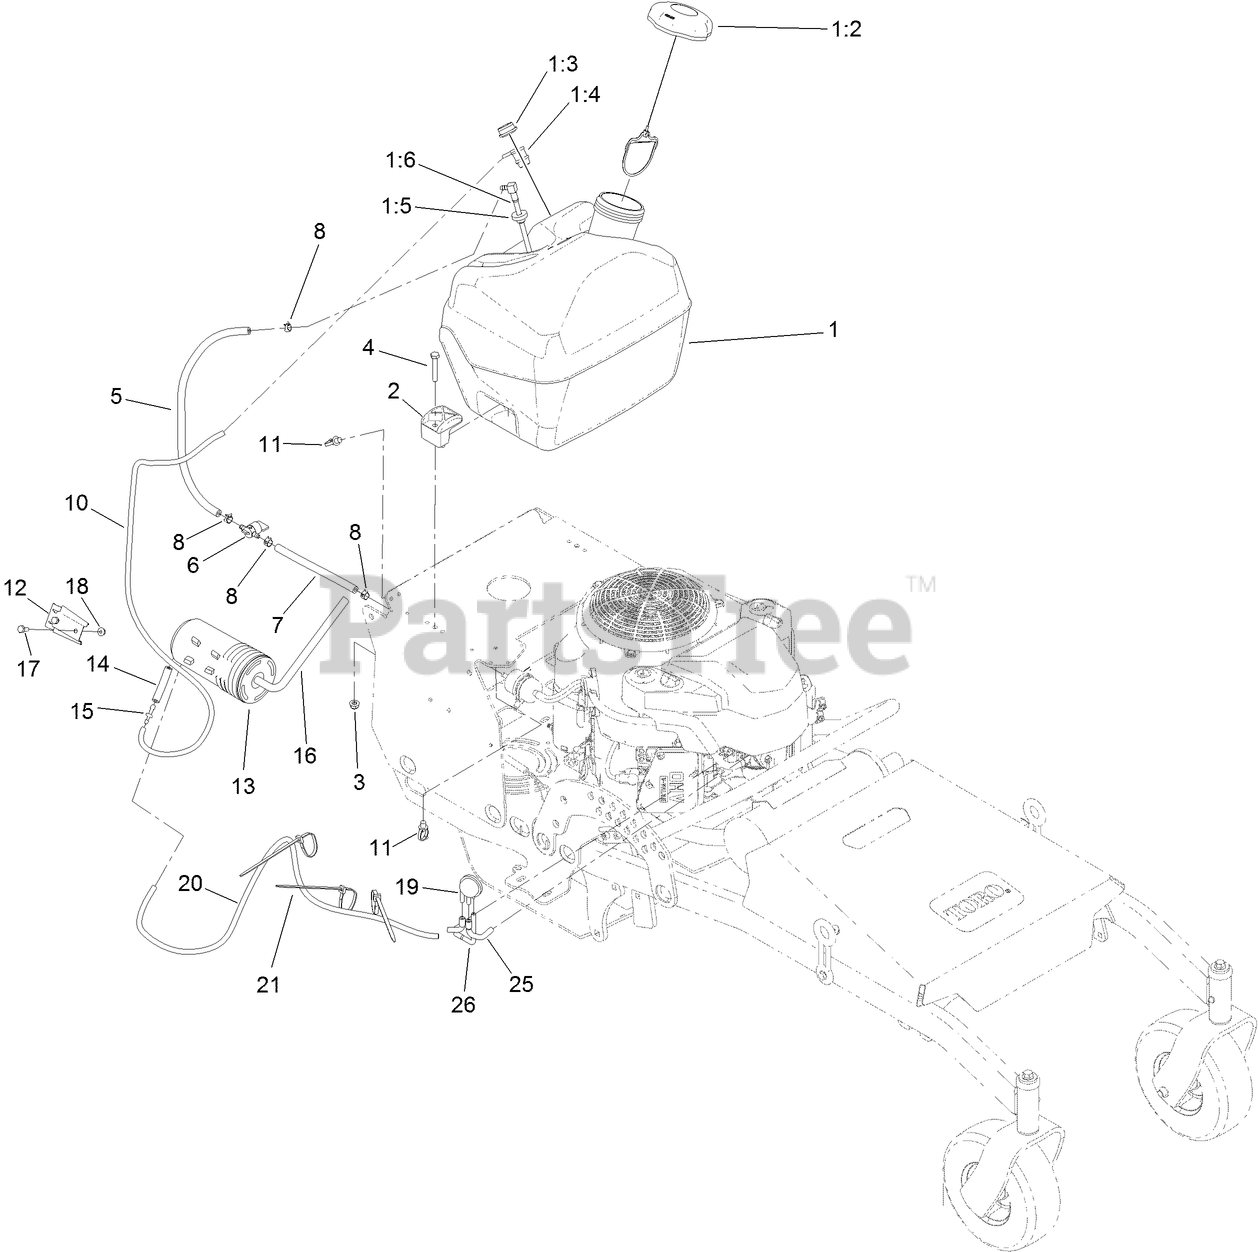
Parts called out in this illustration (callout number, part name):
1	FUEL TANK ASM, 5 GAL
1:2	CAP-FUEL, RATCHETING
1:3	GROMMET
1:4	VALVE-VENT, FUEL
1:5	BUSHING
3	NUT-HF, NI
4	SCREW-HH
5	HOSE-FUEL
6	VALVE-FUEL
7	HOSE-FUEL
8	CLAMP-HOSE
10	HOSE, EMISSIONS
11	CLIP-TIE
12	BRACKET-CANISTER, CARBON
13	CANISTER-CARBON, 800CC
14	HOSE-FUEL
15	FITTING-STRAIGHT
16	HOSE-VENT, CANISTER
17	SCREW-HH
18	NUT-HF
19	VALVE-CONTROL, VACUUM
20	HOSE,VENT,FORMED
21	TIE-CABLE
25	HOSE-VENT, FORMED
26	HOSE-VENT, FORMED
